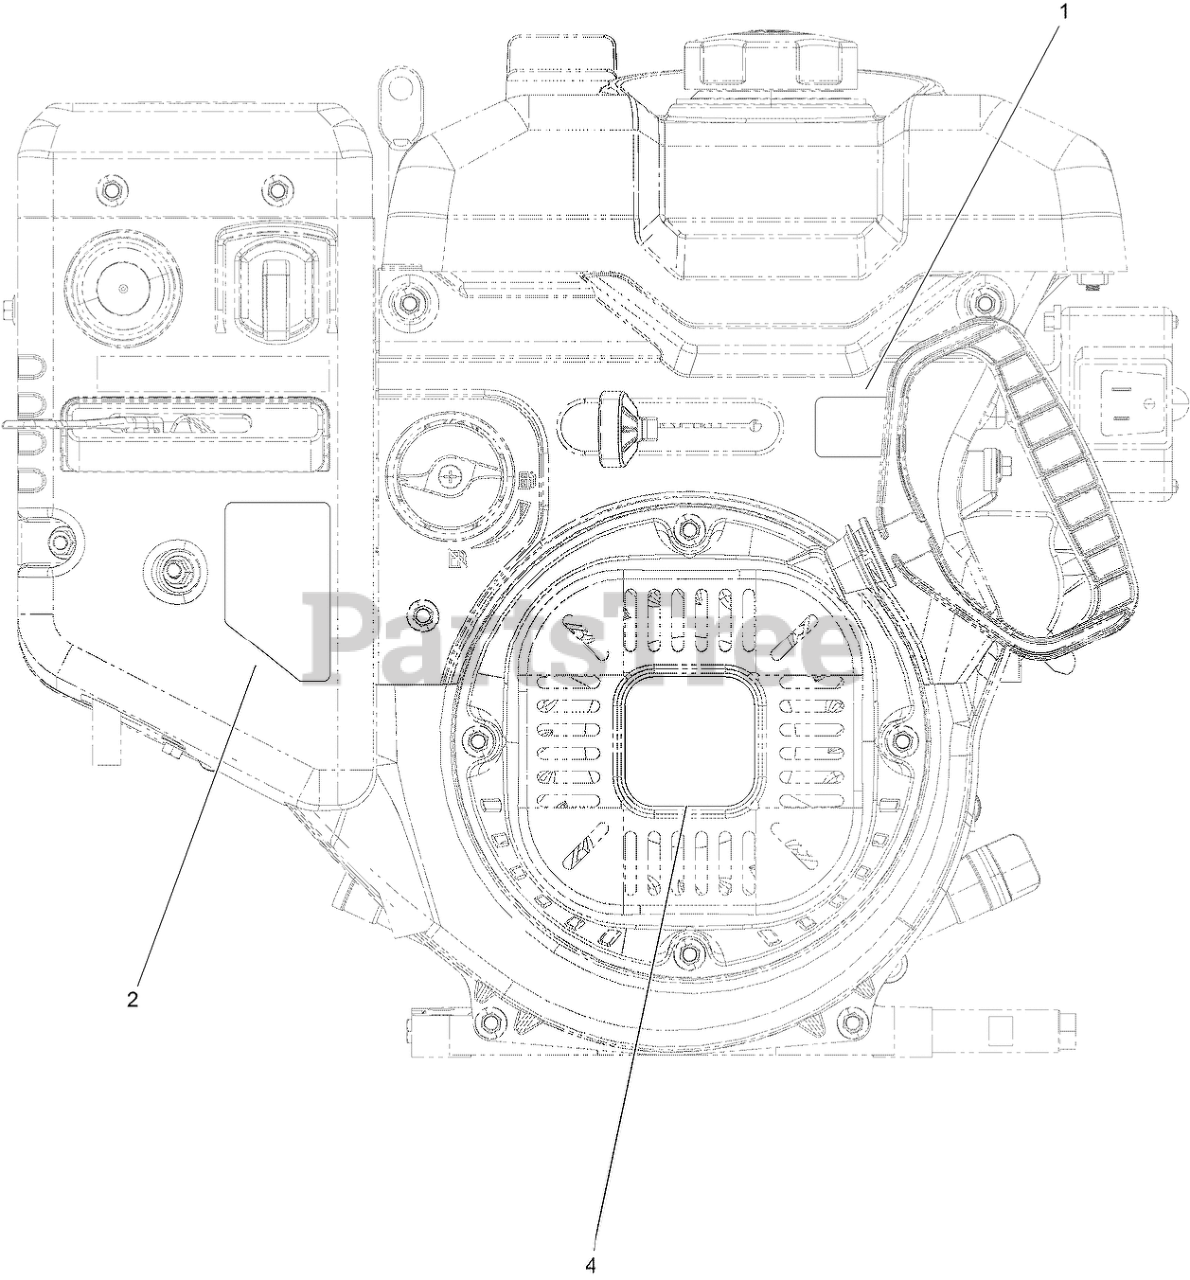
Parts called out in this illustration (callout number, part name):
1	DECAL-THROTTLE
2	DECAL-CONTROL, ENGINE
4	DECAL-RECOIL, G250
